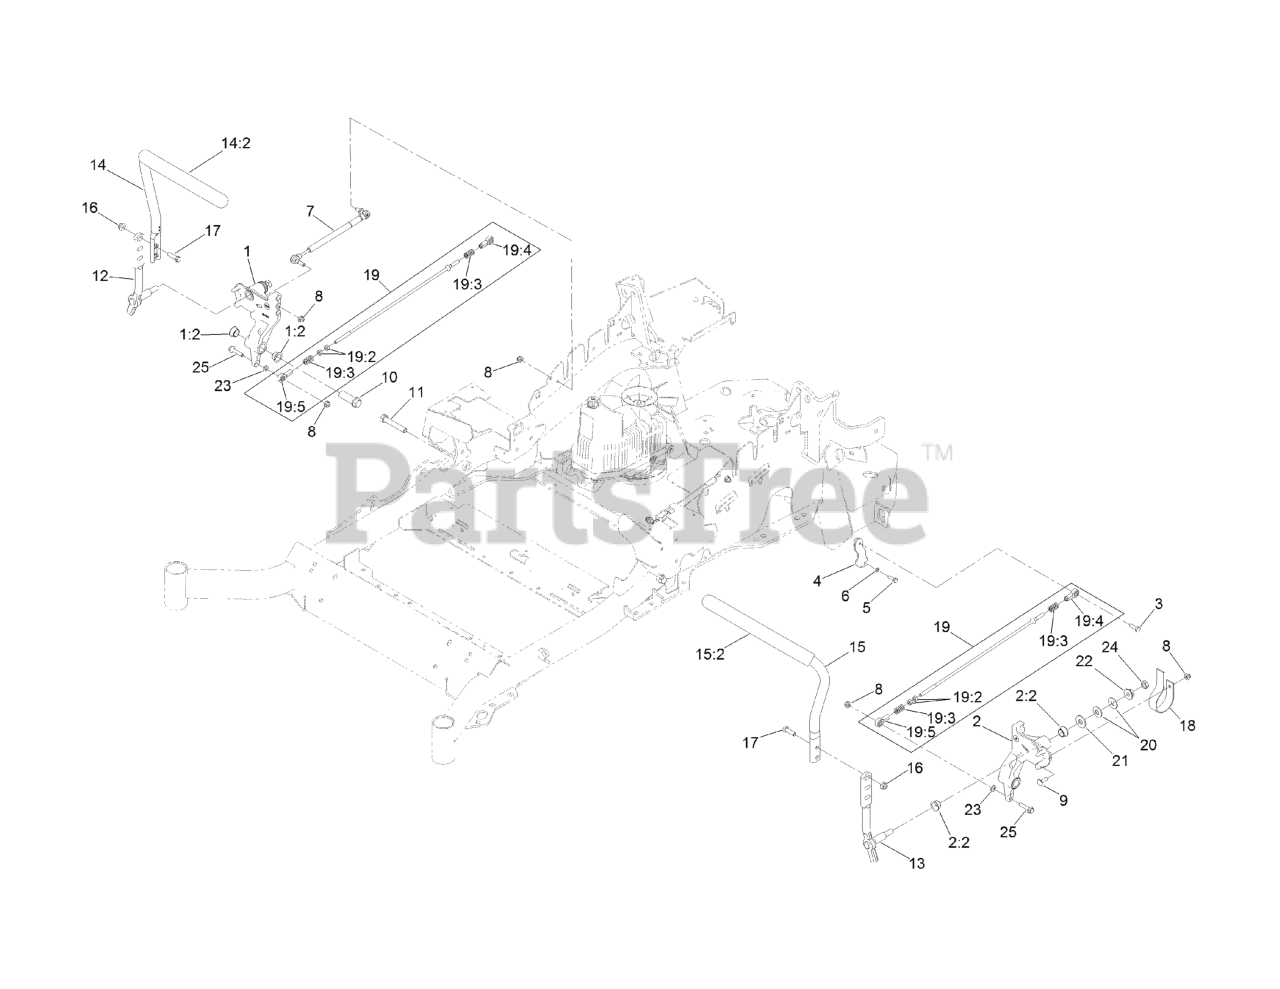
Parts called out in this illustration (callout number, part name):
1	RH MOTION CONTROL AND BUSHING ASM
1:2	BUSHING-FLANGE
2	LH MOTION CONTROL AND BUSHING ASM
2:2	BUSHING-FLANGE
3	SCREW-HH, THREAD LOCKING
4	ARM-CONTROL, PUMP
5	SCREW-HH
6	WASHER-SPRING
7	DAMPER-CONTROL, MOTION
8	NUT-HF, NI
9	BOLT-CARR
10	HUB-THREADED
11	SCREW-HH
12	LEVER-CONTROL MOTION, RH
13	LEVER-CONTROL MOTION, LH
14	RH STEERING HANDLE ASM
14:2	GRIP-LEVER, CONTROL
15	LH STEERING HANDLE ASM
15:2	GRIP-LEVER, CONTROL
16	NUT-HF, NI
17	SCREW-HH
18	SPRING-LEAF
19	FRONT PUMP LINKAGE ASM
19:2	NUT-HEX
19:3	SPRING-COMPRESSION
19:4	BALLJOINT-LH
19:5	BALLJOINT-RH
20	WASHER-SPRING
21	WASHER-FLAT
23	WASHER-PLAIN
24	NUT-JAM
25	SCREW-HHF
